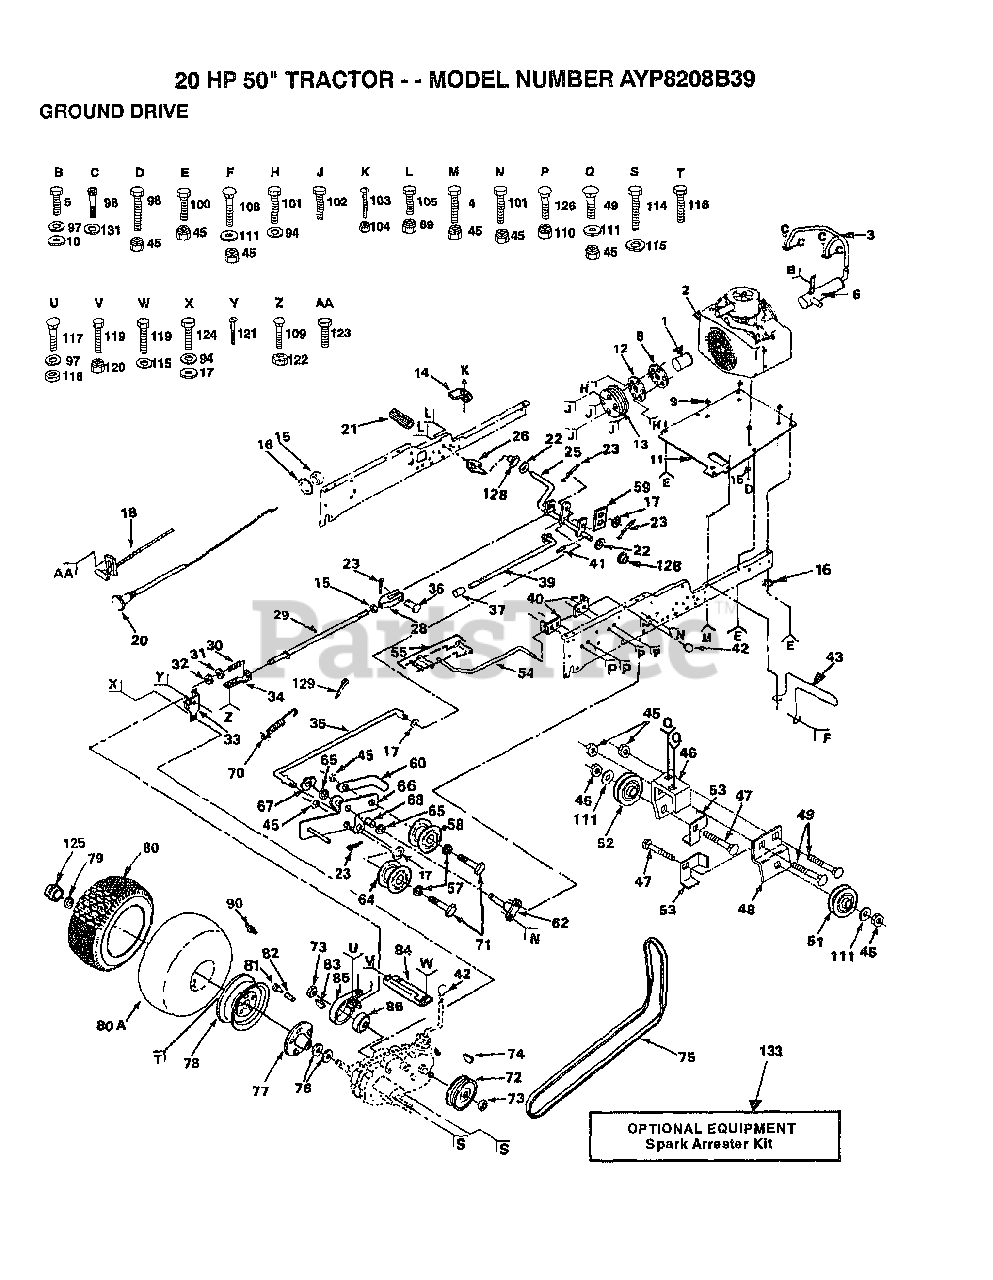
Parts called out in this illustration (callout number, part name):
3	EXHAUST TUBE T
4	"BOLT,HEX"
6	MUFFLER EXHAUST
8	CHAFF GUARD T
9	SPACER.ENGINE KOH
11	"ENG. T, BASE"
12	ADAPTER T
14	ACT-SWITCH T
16	LOCKWASHER
17	WASHER
21	PEDAL COVER T
22	WASHER
25	SHAFT ASSY GT
26	BRKT SWITCH GT
28	YOKE GTV
29	BRAKE ROD T
30	SPRING T
31	WASHER
33	BRAKE BRKT ASSY T
34	GUIDE ROD T
35	ROD CLUTCH GTV
36	CLEVIS PIN T
37	PLUNGER CAP T
39	BRAKE ROD
40	ROD BRACKET GT
41	ROLL PIN STD
42	KNOB
43	GUARD MUFFLER HYT
47	BOLT
48	BRKT IDLER FLAT
49	BOLT
51	IDLER-FLAT T
52	PULLEY V IDLR GTV
53	GUARD BELT
54	ROD SHIFT HI LO
55	CONNECTING LINK
57	WASHER
59	RETAINER SPRING
60	RETAINER BELT
62	BRACKET ASSY GTV
65	WASHER T
66	BRACKET CLUTCH
67	KLIP RING
68	"LY, BEARING"
70	SPRING EXT CLUTCH
73	NUT STD
75	BELT-V.98.5.GD.DV
76	WASHER T
79	KLIP RING
80A	TUBE.23X8/10-12
81	VALVE CAP
82	VALVE STEM LT
85	BRAKE BAND ASM
86	BRAKE DRUM T
89	NUT
94	LOCKWASHER
96	SCREW
97	LOCKWASHER
101	BOLT
102	SCREW
103	SCREW
105	BOLT LT
108	BOLT.3/8-14X1.25
111	WASHER GT
114	BOLT
115	LOCKWASHER
117	BOLT T
119	BOLT
120	NUT GTV
121	SCREW
123	SCREW LT
125	"COVER, HUB"
126	BOLT
128	NYLINER T
129	COTTER PIN
133	SPARK ARREST KIT
903	ZERK FITTING M
